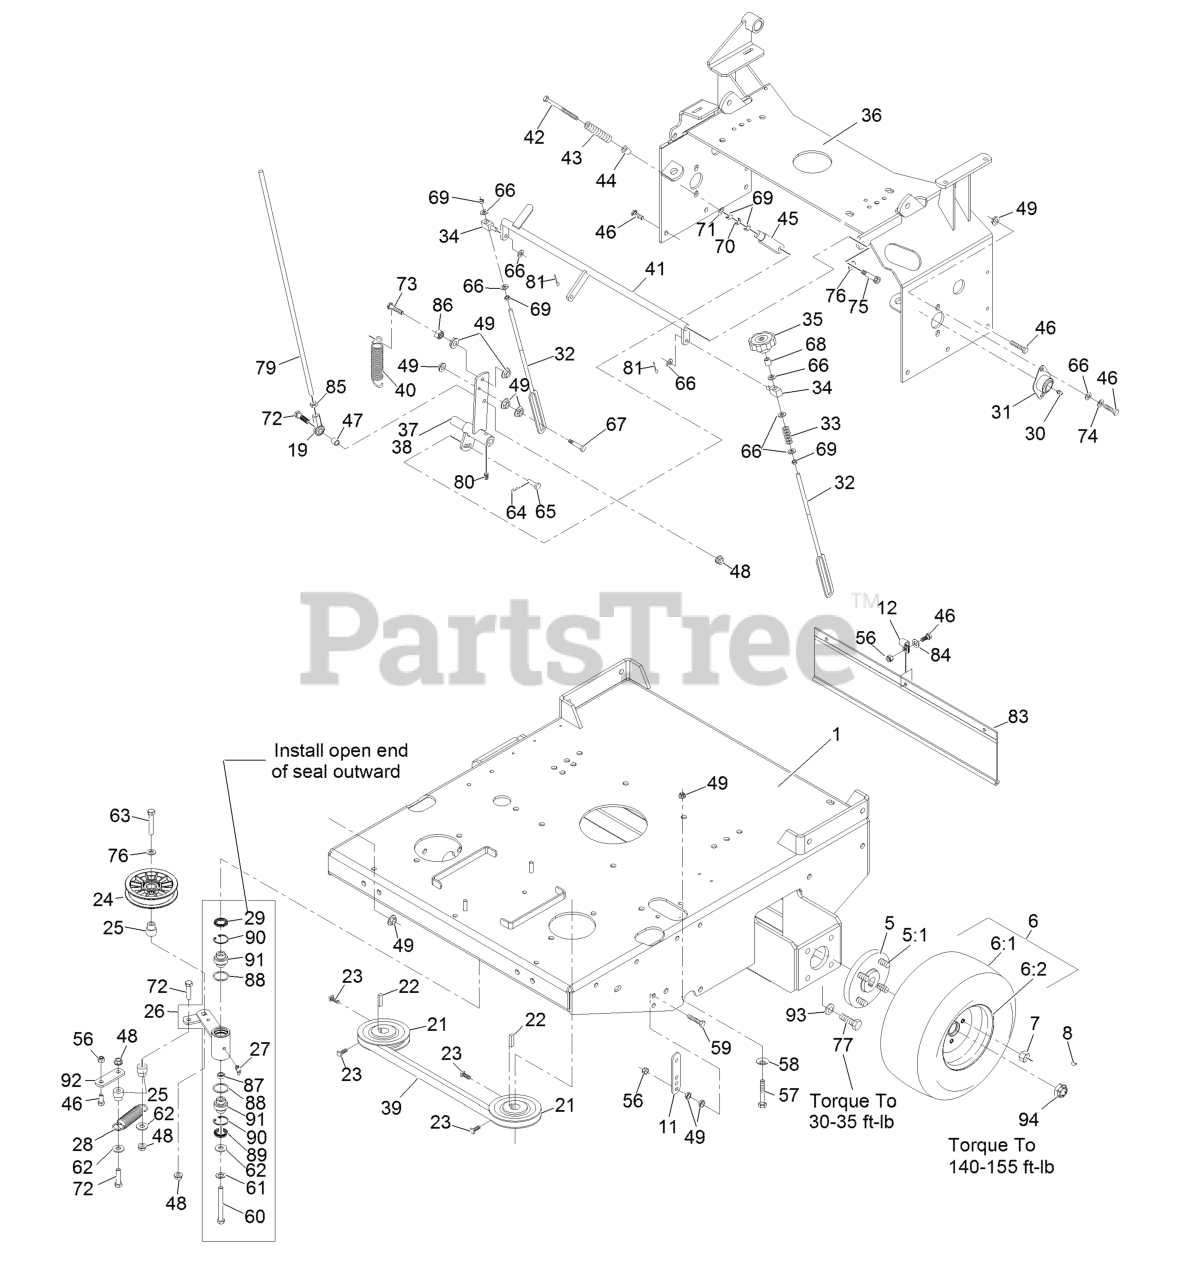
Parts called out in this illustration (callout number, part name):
1	KIT, TTX ENG DECK W/DECAL
5	WHEEL HUB ASM
5:1	STUD-WHEEL
6	ASM, DRIVE TIRE
7	NUT-LUG
8	KEY-WOODRUFF
11	TAB-SPRING, EXTENSION
12	CLIP-LOOM
19	JOINT-BALL END, LH
21	SHEAVE ASM
23	SCREW-SET, SQH
24	PULLEY-IDLER, FLAT
25	BUSHING-IDLER
26	KIT,IDLER ARM W/BRGS.
27	FITTING-GREASE, 90 DEG
28	SPRING-EXTENSION
29	SEAL-LIP, SINGLE
30	FITTING-GREASE
31	BEARING-FLANGE, SIDE
32	LINK,SPEED CONTROL
33	SPRING-COMPRESSION
35	KNOB-TRACKING
36	WLD,FUEL TANK SUPPORT TT
37	WLD,LH CONTROL ARM
39	BELT,COG A-59.5
40	SPRING-EXTENSION
41	WLD,CRANK SPEED CNTRL
42	BOLT-RETURN, NEUTRAL
43	SPRING,COMPRESSION (NEUT)
44	BUSHING-FLANGED
45	YOKE-ADJUSTABLE
46	SCREW-HH
47	TUBE,PUMP LINK SPACER
48	NUT-HHF, WHIZ
56	NUT-LOCK, NI
57	SCREW-HH
58	WASHER-SPRING
59	BOLT-TAP, HH
60	SCREW-HH
61	WASHER-LOCK
62	WASHER-FLAT
63	SCREW-HH
64	PIN-COTTER
65	PIN-CLEVIS
66	WASHER-PLAIN
67	SCREW-HH
69	NUT-HEX
70	NUT-JAM
71	WASHER-FLAT
72	SCREW-HH
73	SCREW-HH, SPECIAL
74	WASHER-LOCK
75	SCREW-HSH
76	WASHER-FLAT
77	SCREW-HH
79	LINK,DRIVE (PLTD)
80	SCREW-SET
81	PIN-COTTER
83	SHIELD,DRAG
84	WASHER-FLAT
85	NUT-HEX JAM, LH
86	NUT-JAM
89	SEAL-LIP, DOUBLE
90	RING-SNAP
91	BEARING-SPHERICAL
92	ARM-LIFT, DECK
93	WASHER-BELLEVILLE
94	NUT-LOCK
